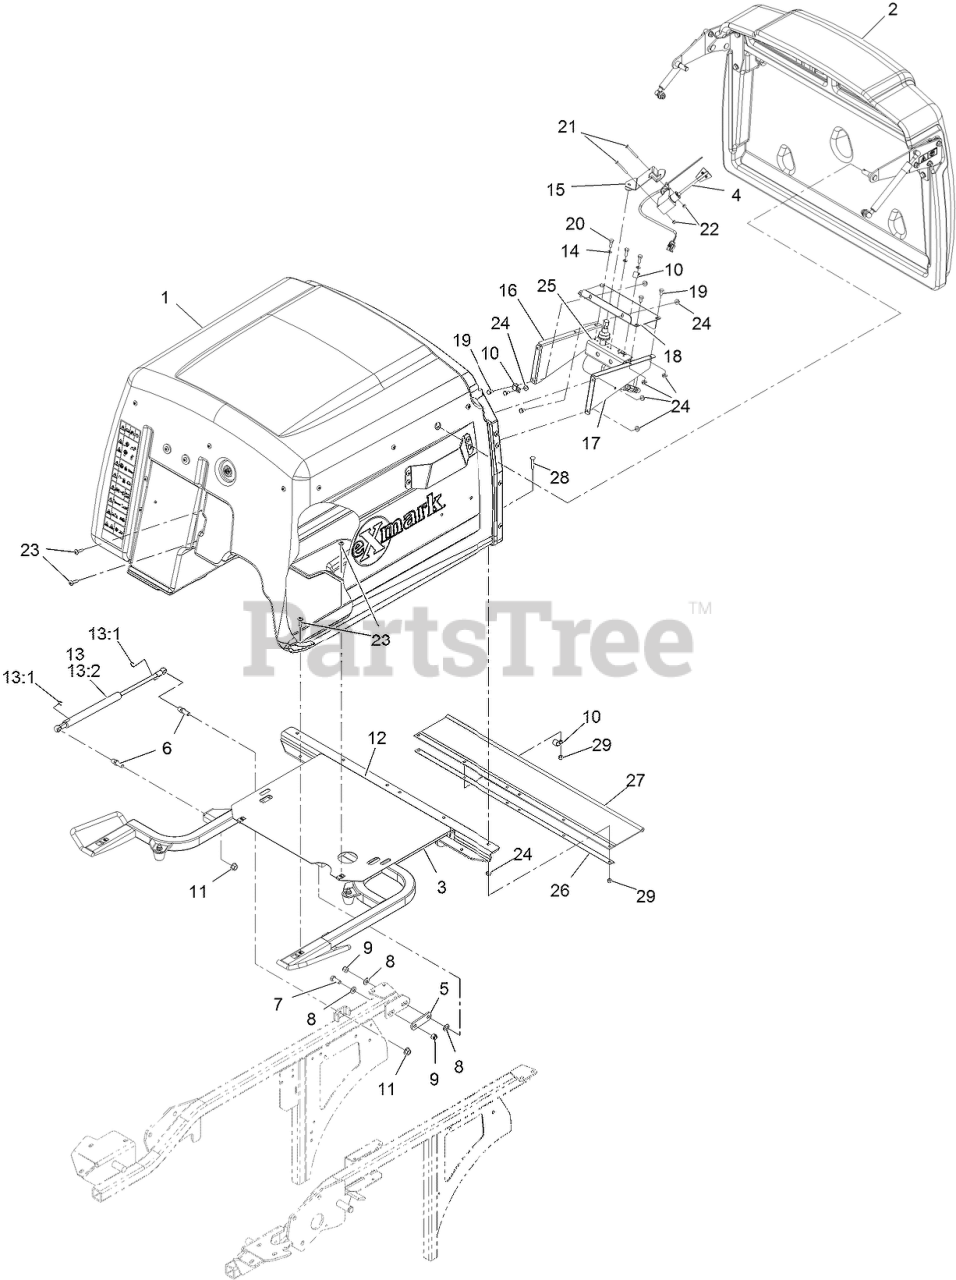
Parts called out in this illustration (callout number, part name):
1	ASM,HOPPER
1	Hopper ASM
2	ASM,DOOR HOPPER
3	HOPPER FRAME ASM
4	FILL SENSOR ASM
5	ARM-LIFT, DECK
6	STUD-BALL
7	SCREW-HH
8	WASHER-FLAT
9	NUT-LOCK, NI
10	CLIP-LOOM
12	SCREW-SHOULDER, HWH
13	DAMPER KIT
13:1	CLIP-RETAINER
13:2	SHOCK-COMPRESSION, GAS
14	WASHER-SPRING
15	MOUNT-SWITCH
16	BRACKET-DRIVE MOTOR, LH
17	BRACKET-DRIVE MOTOR, RH
18	PLATE-SWITCH
19	SCREW-HH
20	SCREW-HH
21	SCREW-PPH
22	NUT-LOCK, NI
23	SCREW-TTH
25	KIT,FILL SENSOR MOTOR
26	CHANNEL-FRAME, HOPPER
27	DEFLECTOR-GRASS
28	SCREW-CARR
29	NUT-LOCK, NI
